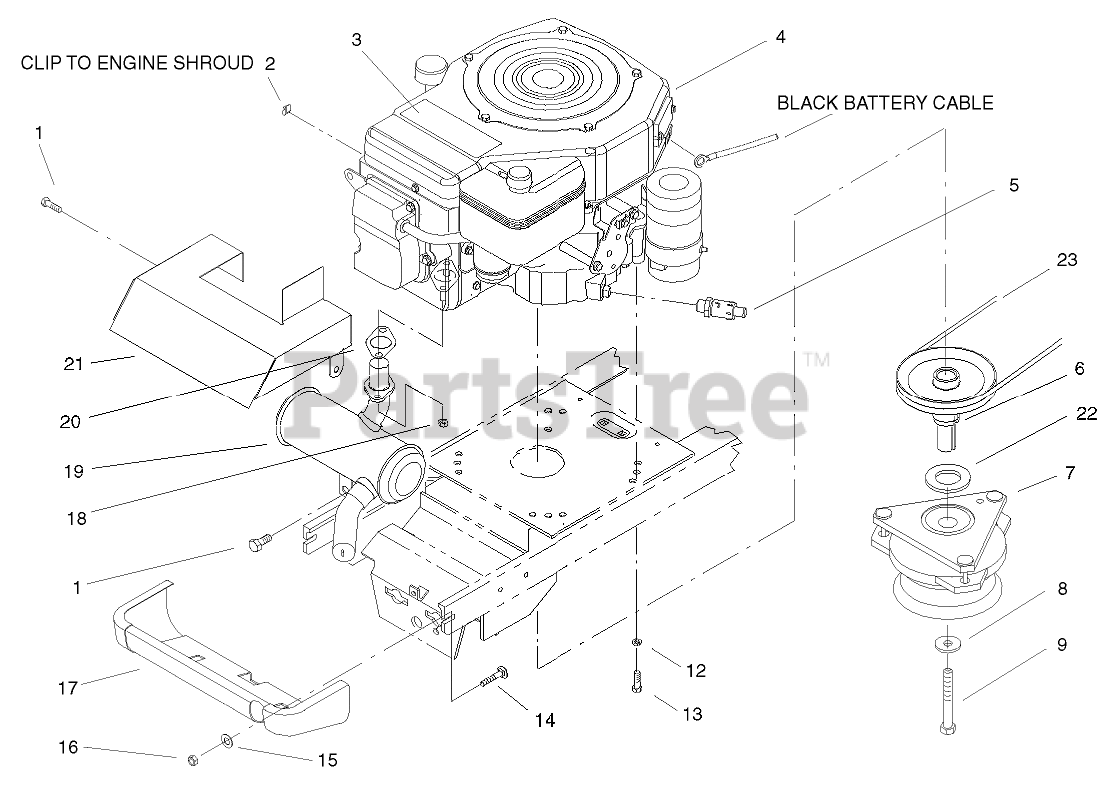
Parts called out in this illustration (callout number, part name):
1	SCREW-HWHTF
2	CLIP-RETAINER, WIRE
3	DECAL - LOGO
4	Engine-Kohler 15 Int-l (only on: 72071)
4	Engine-Kohler 15 (only on: 72050)
5	VALVE-DRAIN, OIL
6	PULLEY-ENGINE
7	Clutch-PTO (only on: 72050)
7	Clutch-Elec PTO (only on: 72071)
8	WASHER
9	SCREW-HH
12	WASHER-LOCK
13	SCREW-HH
14	BOLT-CARR
15	WASHER-FLAT
16	NUT-LOCK, NI
17	MUFFLER SHIELD ASM
18	NUT-HF
19	MUFFLER
20	Gasket-Exhaust
21	SHIELD-MUFFLER
22	SPACER-CLUTCH
23	V-BELT
